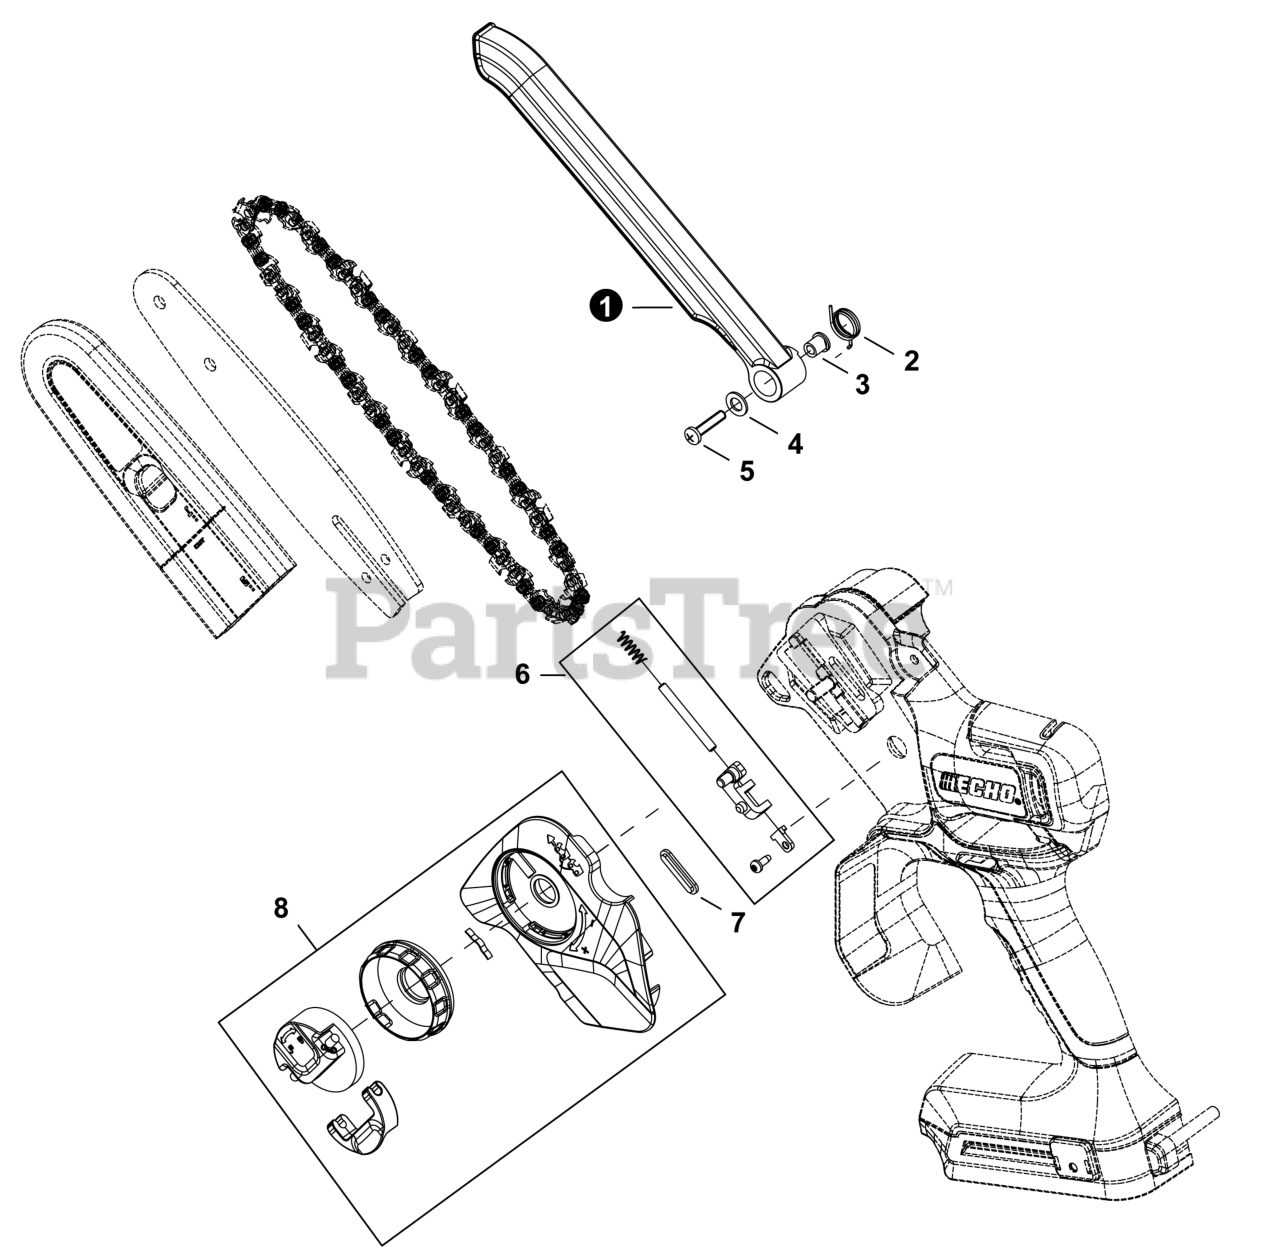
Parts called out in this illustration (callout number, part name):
1	GUARD, CHAIN
6	TENSIONER KIT
7	SEAL, OIL
8	COVER ASSY., SIDE
